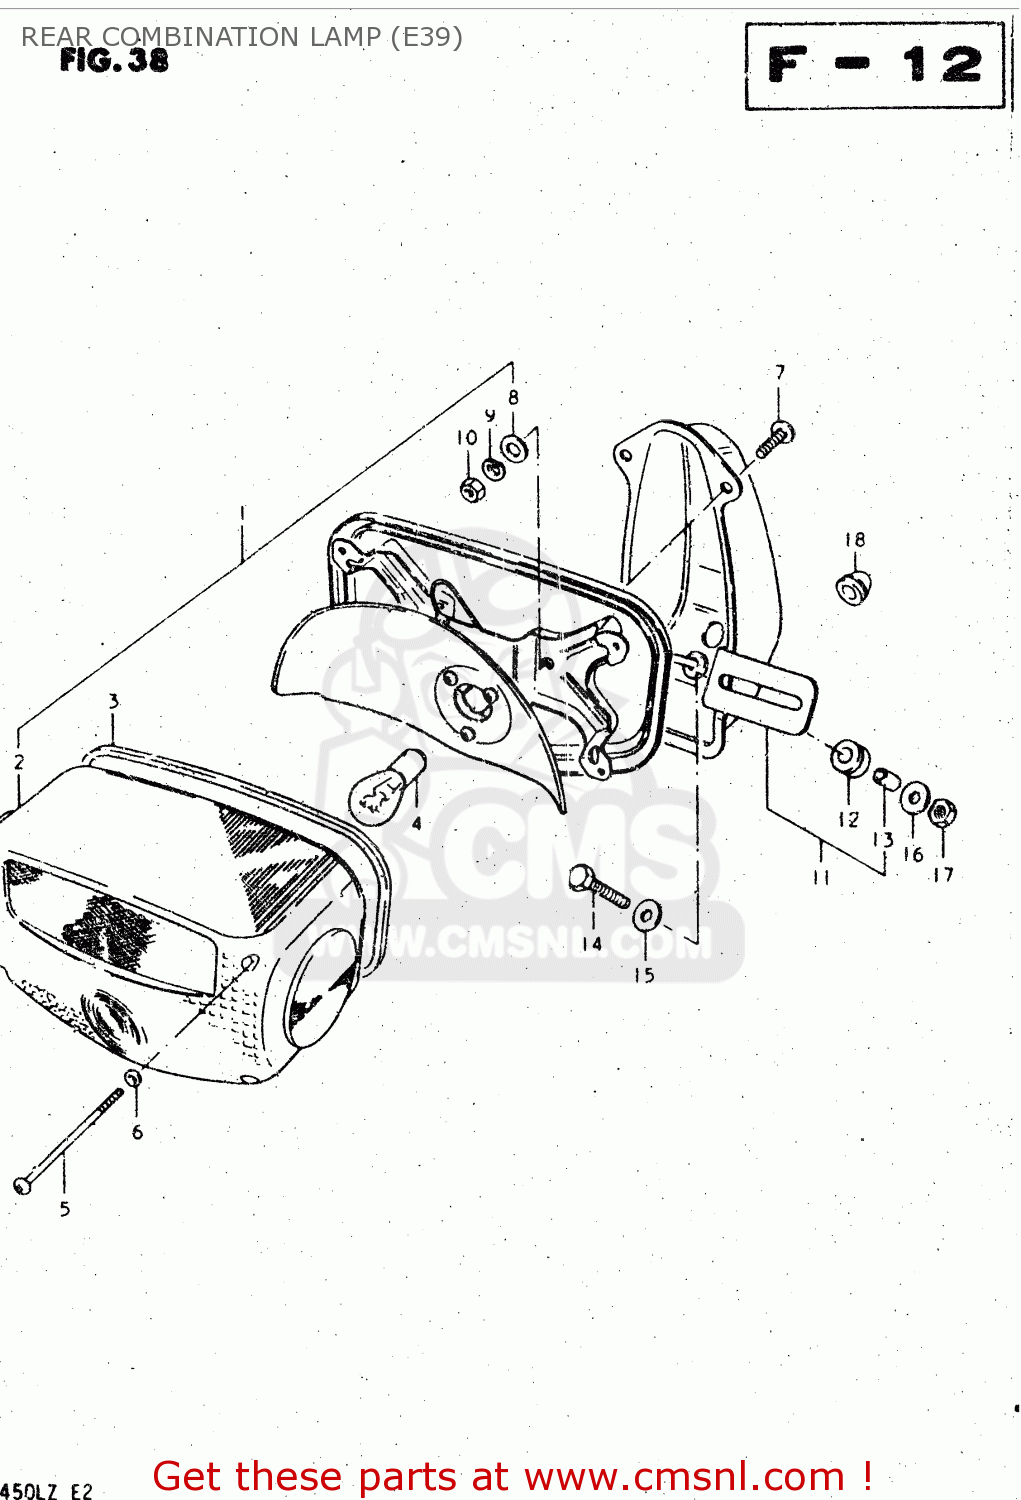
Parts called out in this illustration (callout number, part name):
1	LAMP UNIT, TAIL
2	LENS,REAR COMBINATION LAMP
3	GASKET (NAS)
4	BULB(12V21/5W)
5	SCREW (4X55)
6	GASKET (NAS)
7	SCREW 6X12
8	WASHER
9	LOCK WASHER
10	NUT
11	BRACKET ASSY
12	CUSHION
13	SPACER
14	BOLT
15	WASHER (6.5X20X1.2)
16	WASHER
17	NUT
18	GROMMET
